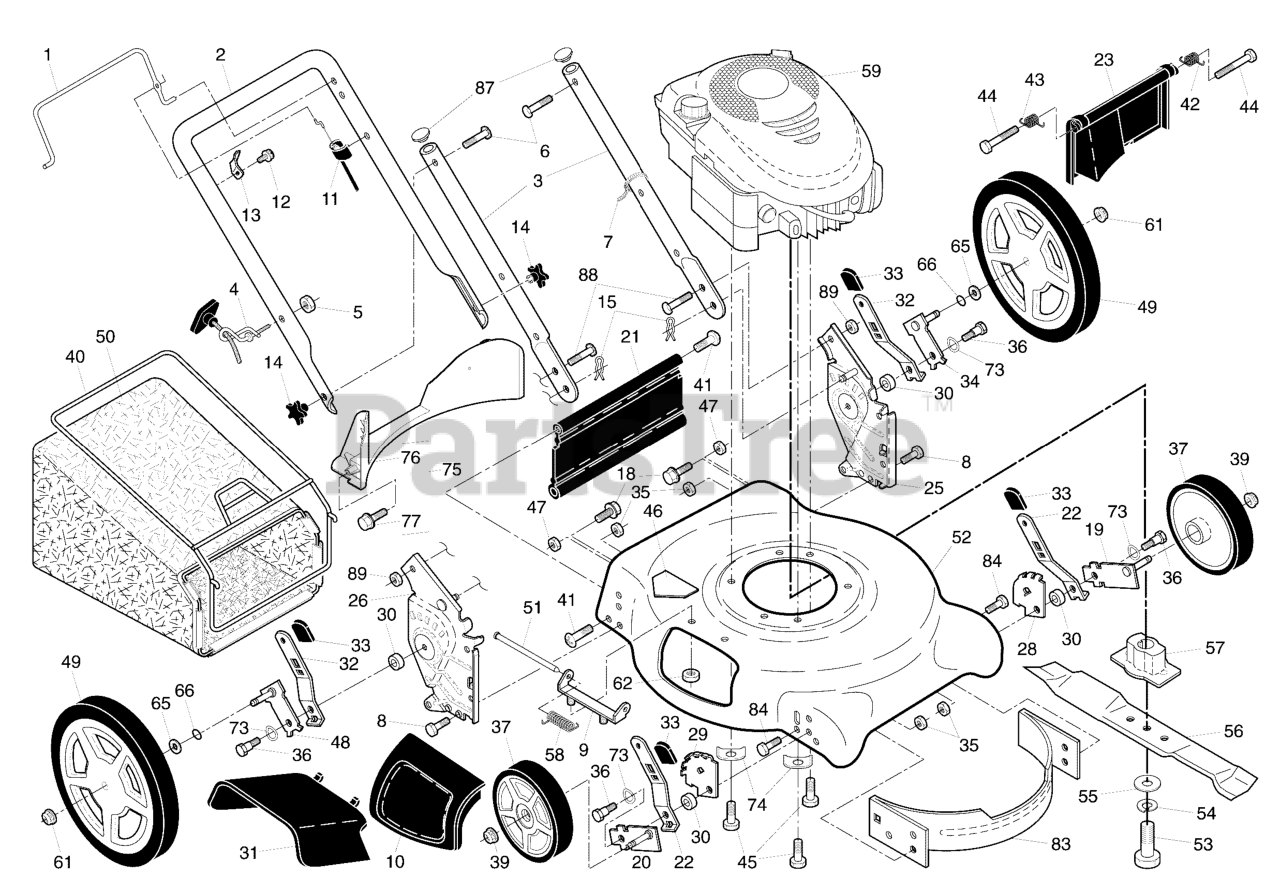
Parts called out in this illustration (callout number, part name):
1	Control Bar
2	Upper Handle
3	Bar, Lower Handle
4	Rope Guide
5	Nut, Hex
6	Handle Bolt
7	Wire Tie
8	Screw
9	Hinge Bracket
10	Mulcher Door
11	Engine Zone Control Cable
12	Screw, Hex Washer Head, #10-16 x 5/8
13	Up-Stop Bracket
14	Handle Knob
15	Hairpin Cotter
18	Screw, Hex Head, Serrated
19	Axle Arm Assy., Front, LH
20	Axle Arm Assy., Front, RH
21	Kit, Rear Skirt
22	Selector Spring, Front
23	Rear Door Assembly
25	Handle Bracket Assy., LH
26	Handle Bracket Assy., RH
28	Wheel Adjusting Bracket, Front, LH
29	Wheel Adjusting Bracket, Front, RH
30	Spacer
31	Discharge Deflector
32	Selector Spring, Rear
33	Selector Knob
34	Axle Arm Assembly, Rear, LH
35	Nut, Hex 5/16-18
36	Shoulder Bolt
37	Wheel & Tire Assembly, Front
39	Nut, Hex
40	Frame, Grassbag
41	Hinge Screw
42	Spring, Rear Door, LH
43	Spring, Rear Door, RH
44	Bolt, Rear Door
45	Screw, Hex Head, Threaded, Rolled, 3/8-16 x 1
46	Danger Decal
47	Nut, Hex
48	Axle Arm Assembly, Rear, RH
49	Wheel & Tire Assembly, Rear
50	Grassbag
51	Hinge Rod
52	Kit, Lawn Mower Housing
53	Screw, Hex Head, 3/8-24 x 1-3/8, Grade 8
54	Helical Lockwasher
55	Hardened Washer
56	21" Blade
57	Blade Adapter
58	Hinge Spring
59	* Engine, Briggs & Stratton
61	** Nut, Hex
62	Nut, Hex
65	Washer, Flat
66	O-Ring
73	Washer, Curved, Cylindrical
74	Washer, Special, Engine
75	Kit, Rear Baffle
76	Baffle, Rear
77	Screw, Rear Baffle
83	Front Baffle
84	Screw, Front Baffle
87	Plug, Handle Bar
88	Bolt, Carriage
89	Nut, Hex
